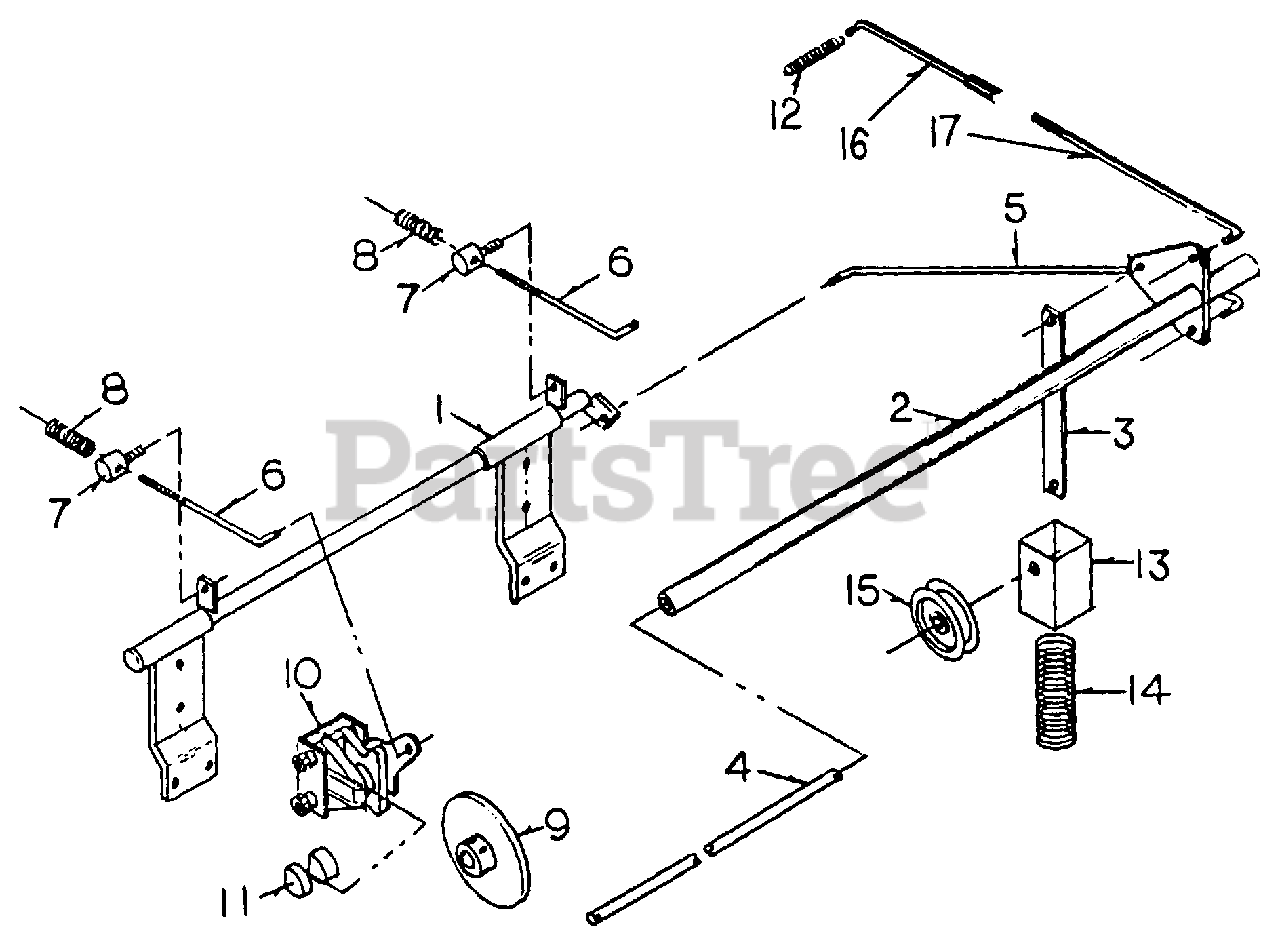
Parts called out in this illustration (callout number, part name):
1	Brake Mount & Cross Rod Ass'y.
2	Brake Clutch Cross Rod
3	Cross Rod to Idler Pulley Linkage
4	Cross Bar Pin
5	Cross Rod to Brake Linkage
7	Caliper Rod Collar
8	Brake Caliper Spring
10	Brake Assembly
12	Brake Pedal Spring
13	Spring Loaded Idler Mount
14	Transmission Belt Idler Spring
15	Idler Pulley
16	Brake Rod, Adjustable
